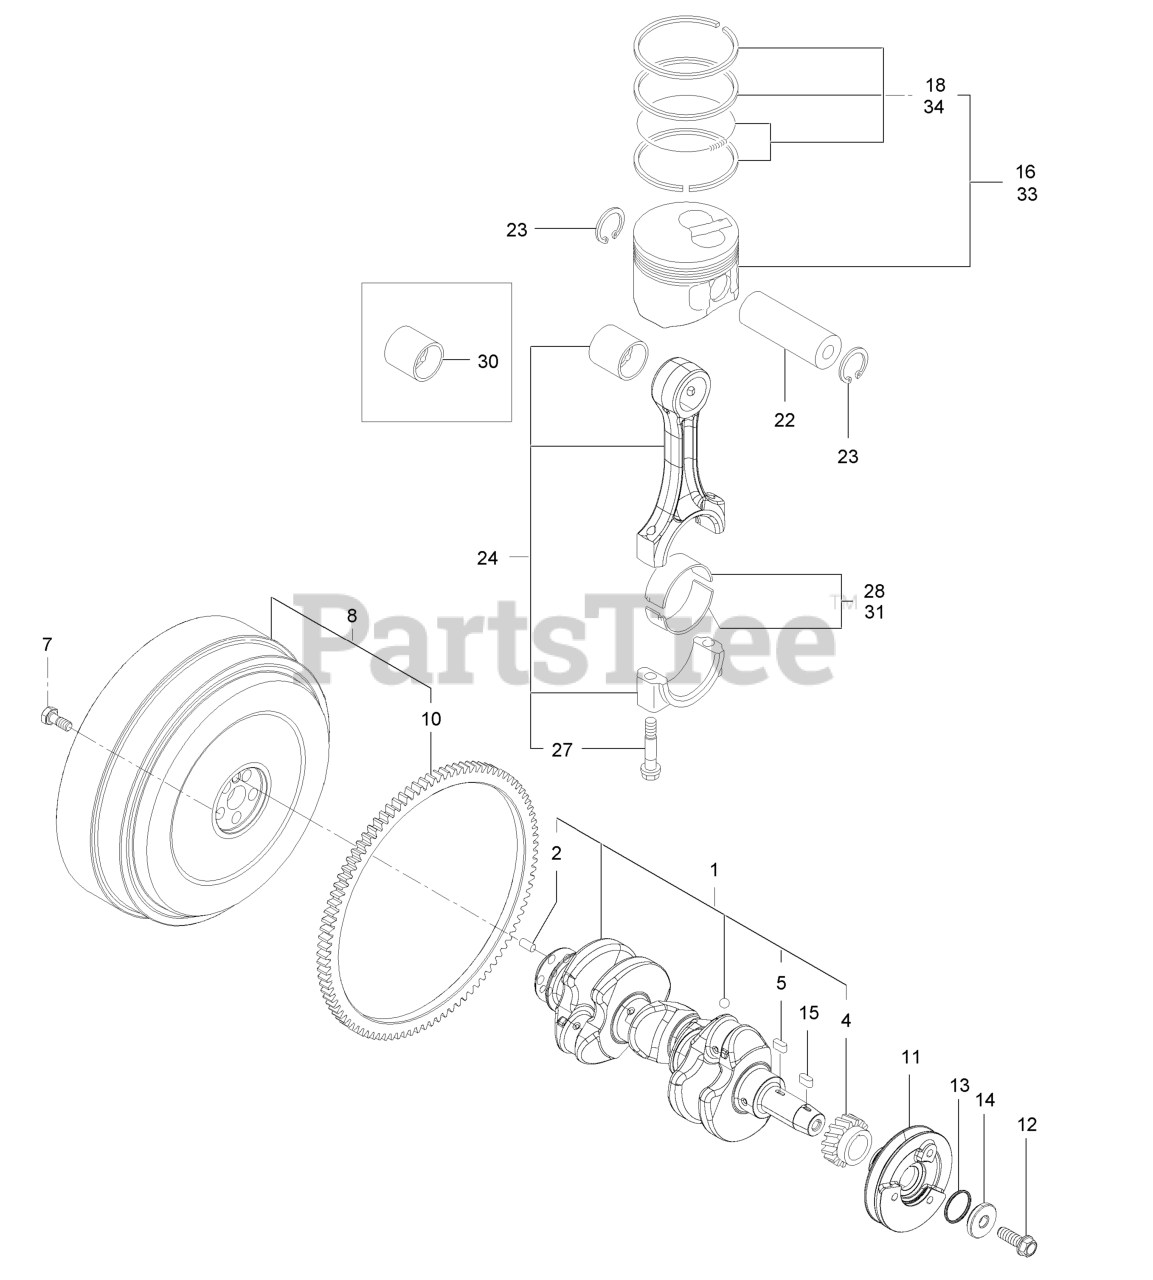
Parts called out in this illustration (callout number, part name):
1	Crankshaft ASM
4	Gear-Crankshaft
7	Bolt, Flywheel 5
8	Flywheel ASM
10	Gear-Ring
11	V-Pulley, Crankshaft 1
12	Bolt, Flange 12X1.25 1
13	Gasket-Washer
16	Piston ASM
18	Ring ASM
22	Pin-Piston
24	Rod ASM-Connecting
27	Bolt-Connecting Rod
28	Bearing-Crank Pin
30	Bearing-Piston Pin
33	Piston ASM
34	Ring ASM
